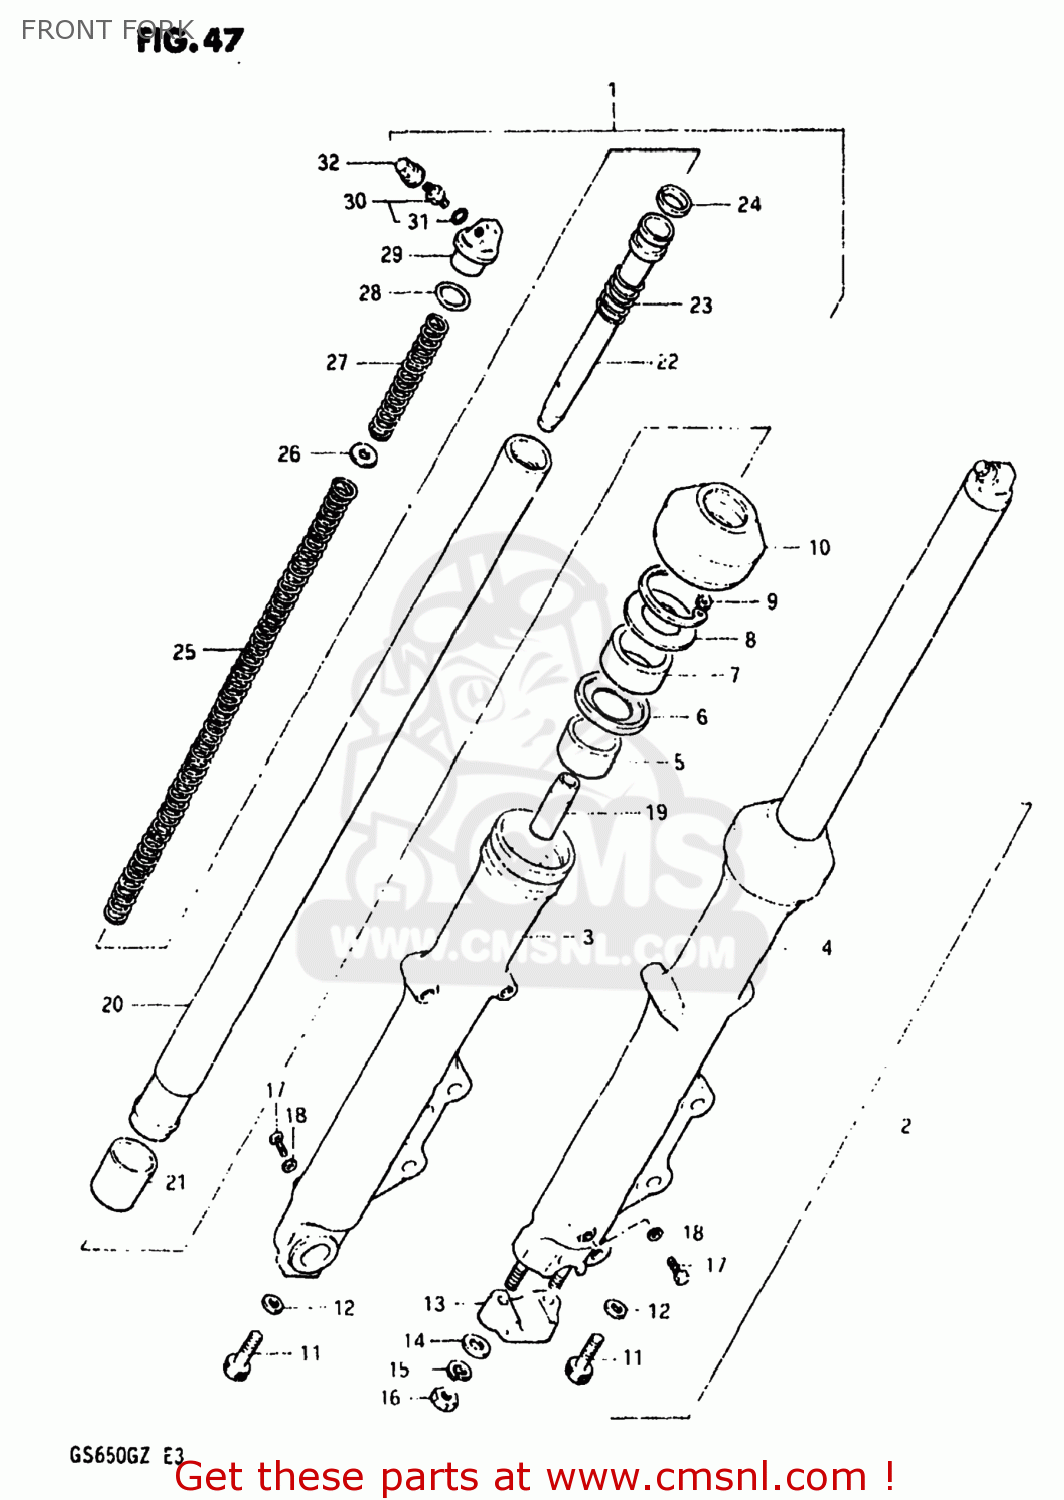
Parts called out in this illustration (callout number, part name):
1	DAMPER ASSEMBLY,RIGHT
2	DAMPER ASSEMBLY,LEFT
3	TUBE,FORK,OUTER,RIGHT
4	TUBE,FORK,LEFT,OUTER
5	BUSH,GUIDE
6	SPACER,SEAL
7	OIL SEAL,FRONT FORK
8	RING,FR FORK
9	CIRCLIP,FORK OIL SEAL
10	BOOT
11	BOLT(8X27)
12	GASKET (NAS)
13	HOLDER,AXLE
14	WASHER
15	LOCK WASHER
16	NUT
17	BOLT(6X8)
18	GASKET,DRAIN,PLUG (NAS)
19	PIECE,OIL LOCK
20	TUBE,FORK,INNER
21	PISTON
22	CYLINDER,FRONT FORK
23	SPRING,FORK REBOUND
24	RING
25	SPRING,FRONT FORK
26	WASHER,SPRING
27	SPRING,FRONT
28	O-RING
29	BOLT,FORK INNER TUBE
30	VALVE,AIR
31	O-RING
32	CAP
